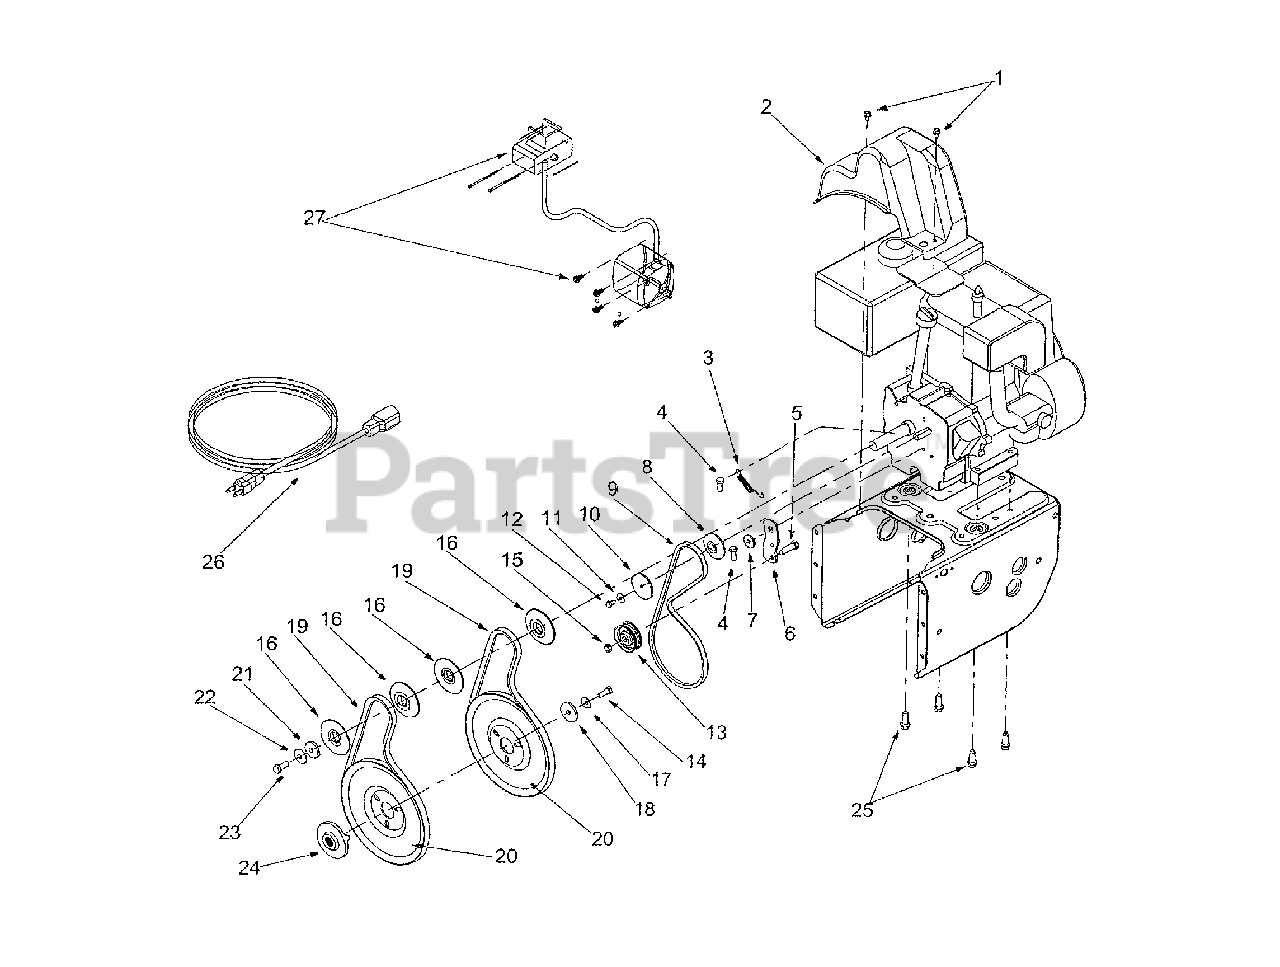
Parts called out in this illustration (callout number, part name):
1	Hex Washer Screw 1/4-20 x .625
2	Belt Cover
3	Extension Spring
4	Hex Screw 5/16-24 x .75
5	Hex Cap Screw 3/8-16 x 1.25
8	Pulley Half
9	V-Belt
10	Pulley Half
11	Bell Washer
12	Hex Cap Screw 1/4-28 x .50
13	Flat Idler
14	Lock Hex Cap Screw 5/16-24
15	Lock Jam Nut 3/8-16
16	Pulley Half
17	Bell Washer
18	Flat Washer
19	Belt
20	Auger Pulley
21	Flat Washer 3/8 x 1.25 OD
22	Bell Washer
23	Hex Cap Screw 3/8-24
24	Adapter Pulley
25	Hex Screw 3/8-16 x 1.0
26	Extension Cord
27	Electric Start
